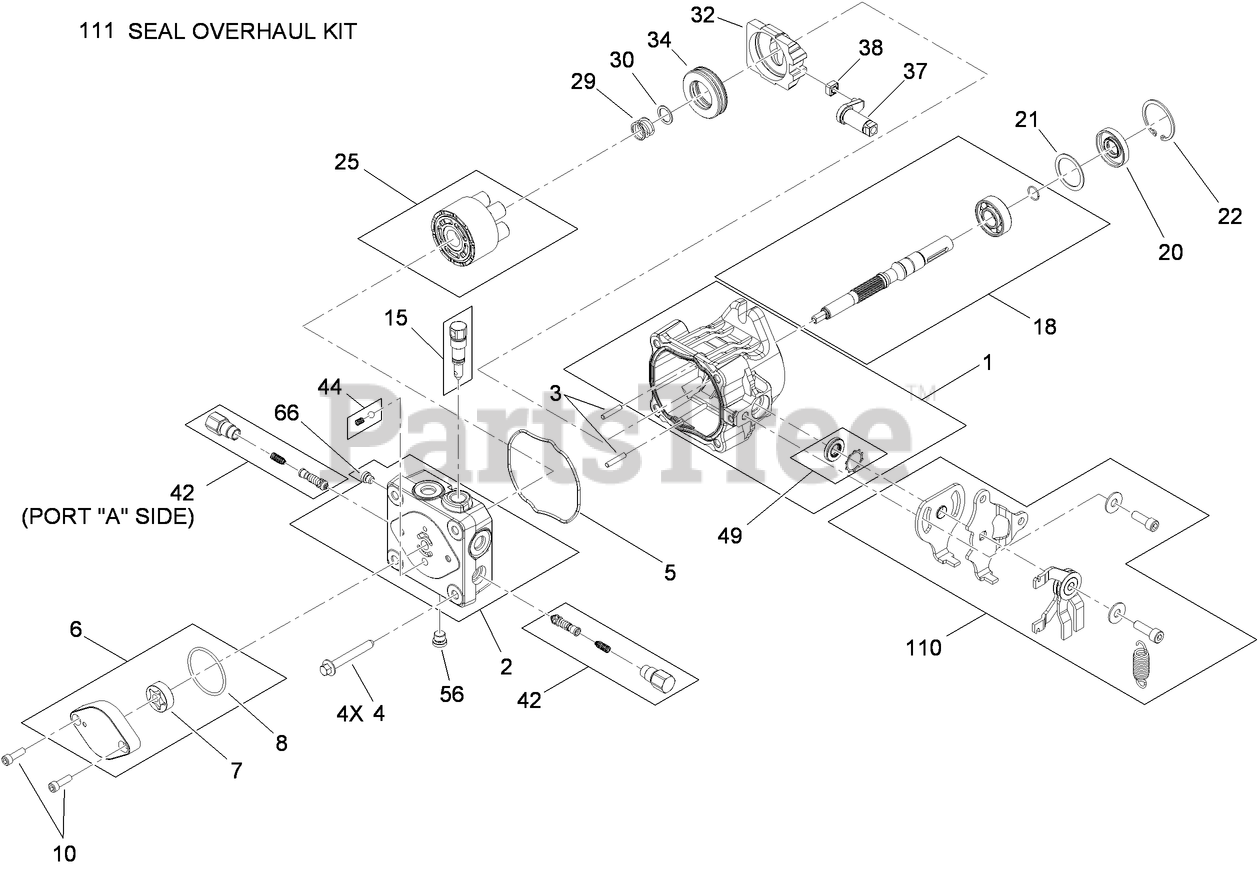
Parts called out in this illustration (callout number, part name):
1	HOUSING KIT
2	END CAP STD CHARGE KIT
3	PIN-HEADLESS, STRAIGHT
4	BOLT-HF
5	O-RING
6	CHARGE PUMP KIT
7	GEROTOR ASM
8	O-RING
10	CAPSCREW
15	BYPASS VALVE KIT
18	INPUT SHAFT KIT
20	SEAL-LIP
21	SPACER
22	RING-RETAINING
25	CYLINDER BLOCK KIT
29	SPRING-BLOCK
30	WASHER-THRUST
32	SWASHPLATE-VARIABLE
34	BEARING-THRUST
37	ARM-TRUNNION, TAPERED SQUARE
38	GUIDE-SLOT
42	VALVE-CHECK (W/POPPET)
44	CHARGE RELIEF KIT
49	TRUNNION SEAL / RETAINER KIT
56	PLUG-HSH
66	PLUG-HSH
110	KIT-RETURN
111	SEAL OVERHAUL KIT
